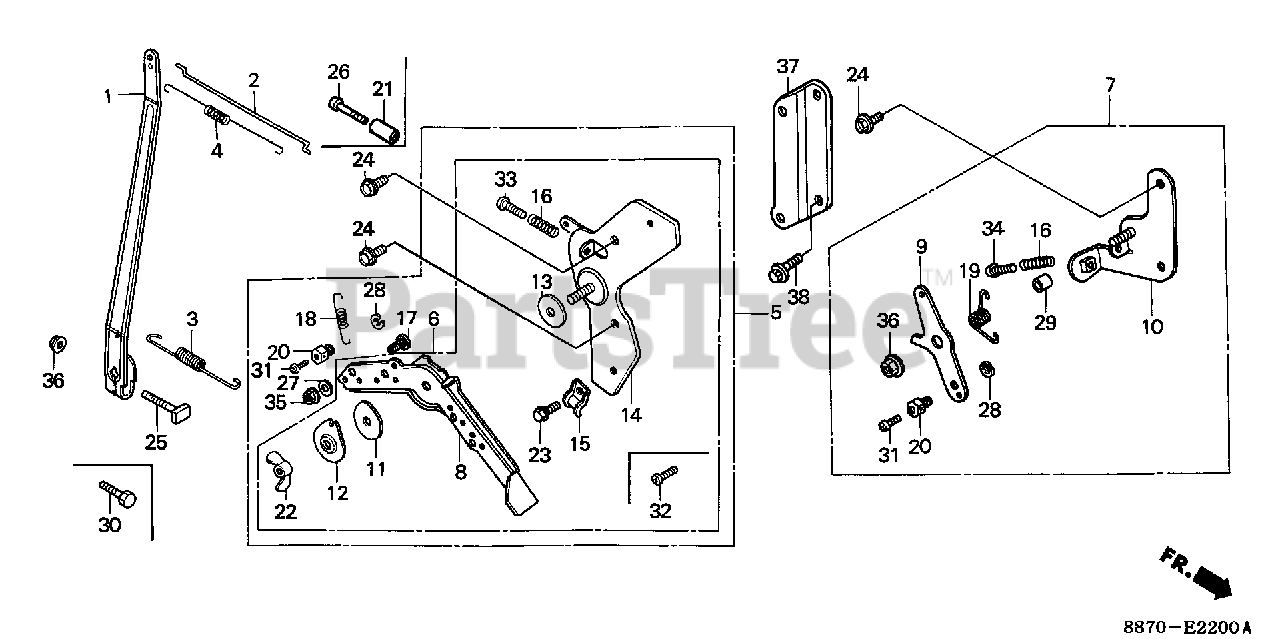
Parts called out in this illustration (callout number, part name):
1	ARM, GOVERNOR
2	ROD, GOVERNOR
3	SPRING, GOVERNOR
4	SPRING, THROTTLE RETURN
5	CONTROL ASSY.
8	LEVER, CONTROL
11	SPRING, LEVER
12	WASHER, CONTROL LEVER
13	SPACER, CONTROL LEVER
14	BASE, CONTROL LEVER
15	HOLDER, CONTROL CABLE
16	SPRING, CONTROL ADJUSTING
22	WINGNUT (6MM)
23	BOLT, FLANGE (5X10)
24	BOLT, FLANGE (6X12) (CT200)
25	BOLT, GOVERNOR ARM
30	BOLT, HEX. (6X20)
32	SCREW, PAN (5X10)
33	SCREW, PAN (5X22)
36	NUT, FLANGE (6MM)
